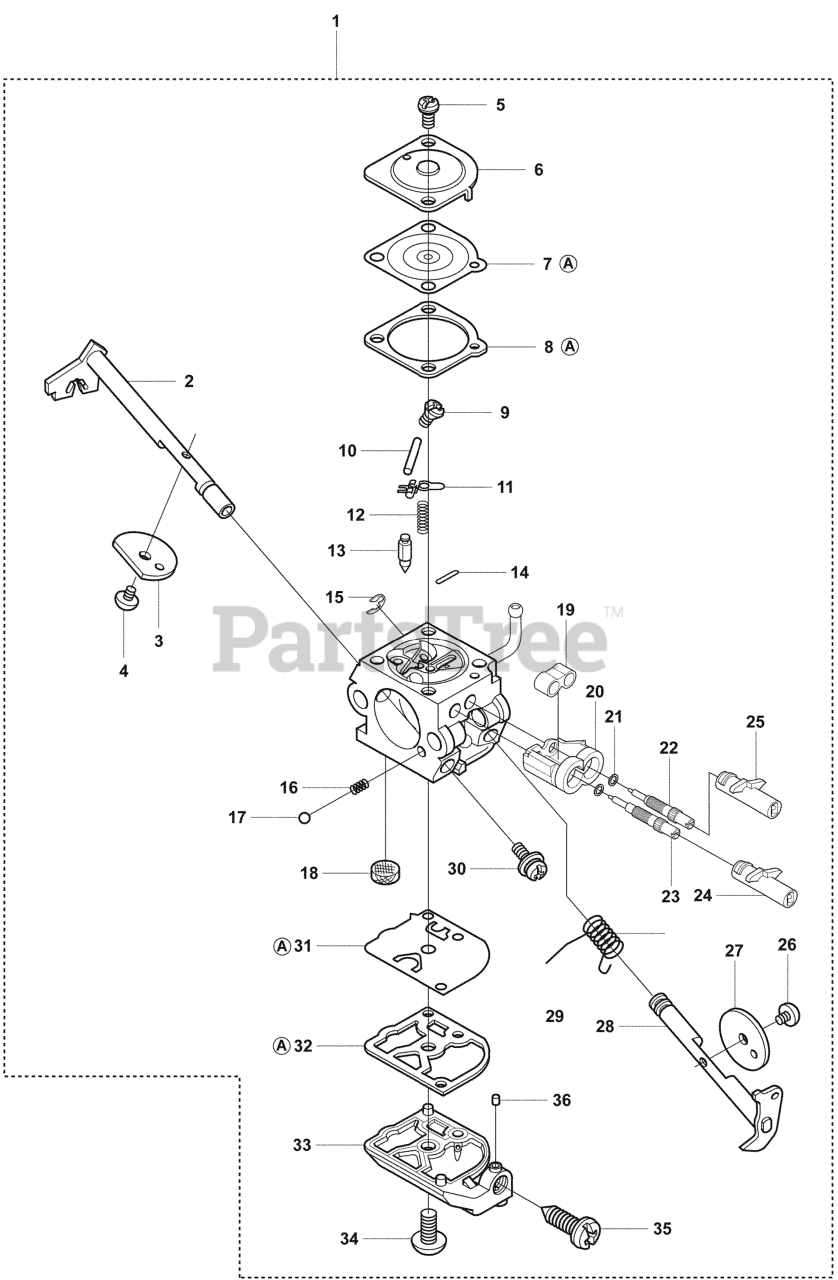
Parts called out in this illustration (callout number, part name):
1	CARBURETOR
7	METERING DIAPHRAGM
8	GASKET METERING SIDE
10	PIN RETAINING SCREW
12	SPRING
13	INLET NEEDLE
22	NEEDLE LOW SPEED
23	NEEDLE HIGH SPEED
24	LIMITER CAP
25	LIMITER CAP
27	THROTTLE FLAP
29	SPRING THROTTLE
31	PUMP DIAPHRAGM
